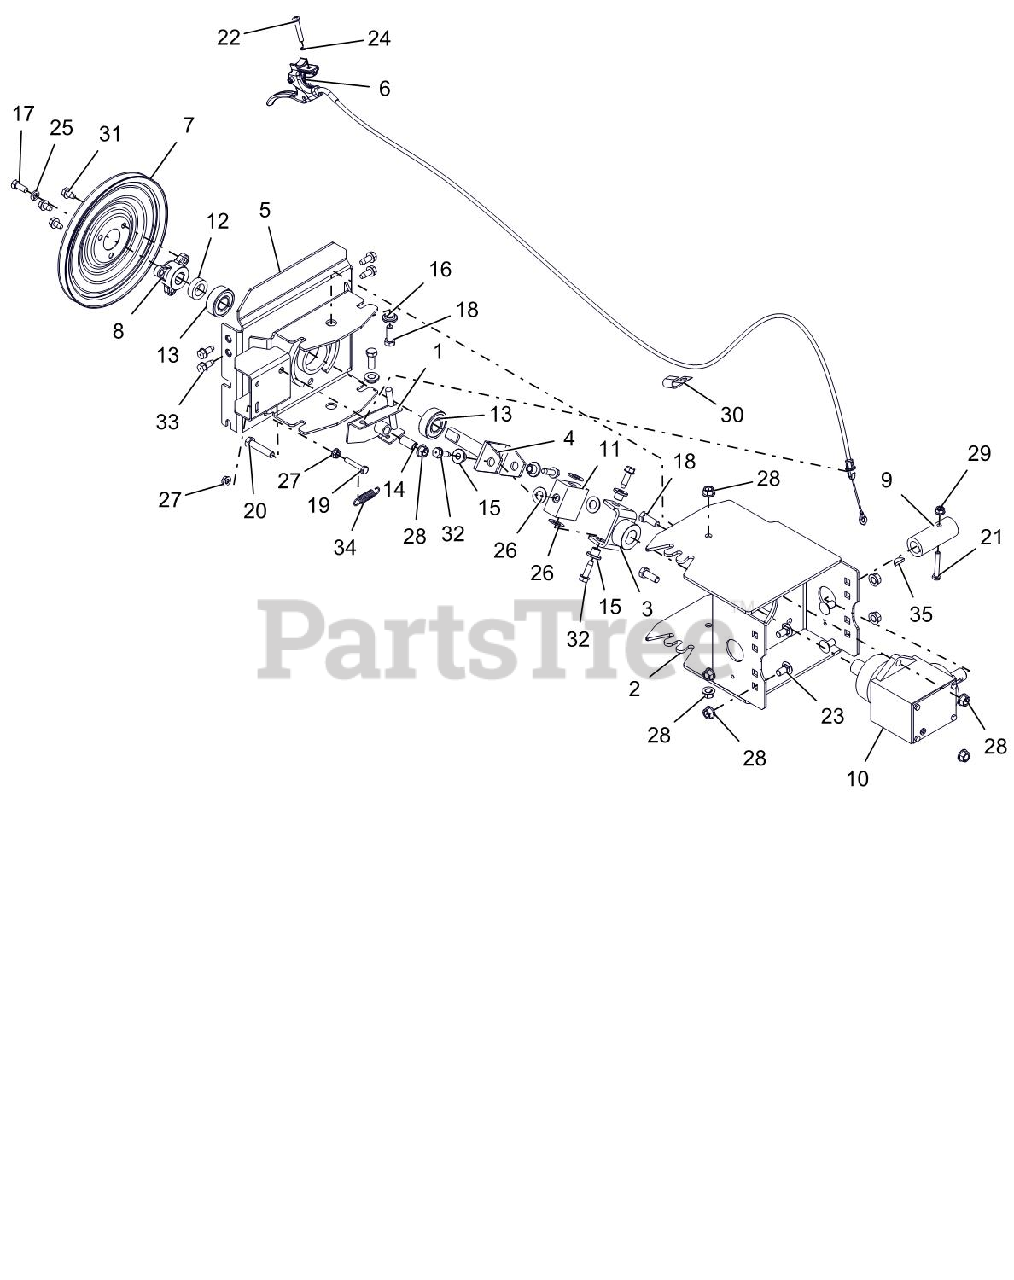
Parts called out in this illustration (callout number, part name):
1	ARM, PIVOT LOCK
2	ADAPTER, BROOM FRAME
3	JOINT,UNIVERSAL
4	JOINT,UNIVERSAL
5	ADAPTER, FRAME-20000 SERIES
6	CABLE, REMOTE BRUSH LOCK
7	PULLEY,SPIN FORM SINGLE GROOVE
8	PULLEY HUB, BOLT-ON D-BORE .75
9	HUB, COUPLING
10	GEAR BOX ASSEMBLY
11	BLOCK, UNIVERSAL
12	SPACER .755X1.250X.370
13	BRG-BALL .750X1.781X.61
14	BSHG-SLV .385X.500X1.045
15	BSHG-FLG .325X.500X.513X.875
16	BSHG-FLG .406X.88X.270X.140
17	BLT-HEX .31-24X.75 YWZC GR5
18	@BLT-HEX .38-16X1.00 GR5 YWZC
19	@BLT-HEX .25-20X1.50 GR5 YWZC
20	@BLT-HEX .38-16X1.75 GR5 YWZC
21	@BLT-HEX .25-20X1.75 GR5 YWZC
22	SCR-MCH .25-20X1.50 OVAL HD
23	@BLT-RDHDSQNK .38-16X.75 G5YZ
24	WSHR-LK-INT .250 TH TYA
25	WSHR-LK .312X.097 HVY YWZC
26	WSHR-HDND-STL-THR.515X.97X.062
27	@NUT-SPNLK-FLG .25-20 YWZC
28	@NUT-LK-TOP-FLG .38-16 YWZC
29	@NUT-LK-TOP-FLG .25-20 YWZC
30	J-CLAMP
31	@SCR-TAP .31-18X.50 HWH TR YWZ
32	@SCR-TAP .31-18X1.00 HWH TR YZ
33	@SCR-TAP .31-18X.75 HWH TR YWZ
34	SG-TENS .06X.46X2.00
35	KEY-WDRF .188X.75X.313 SAE 9
